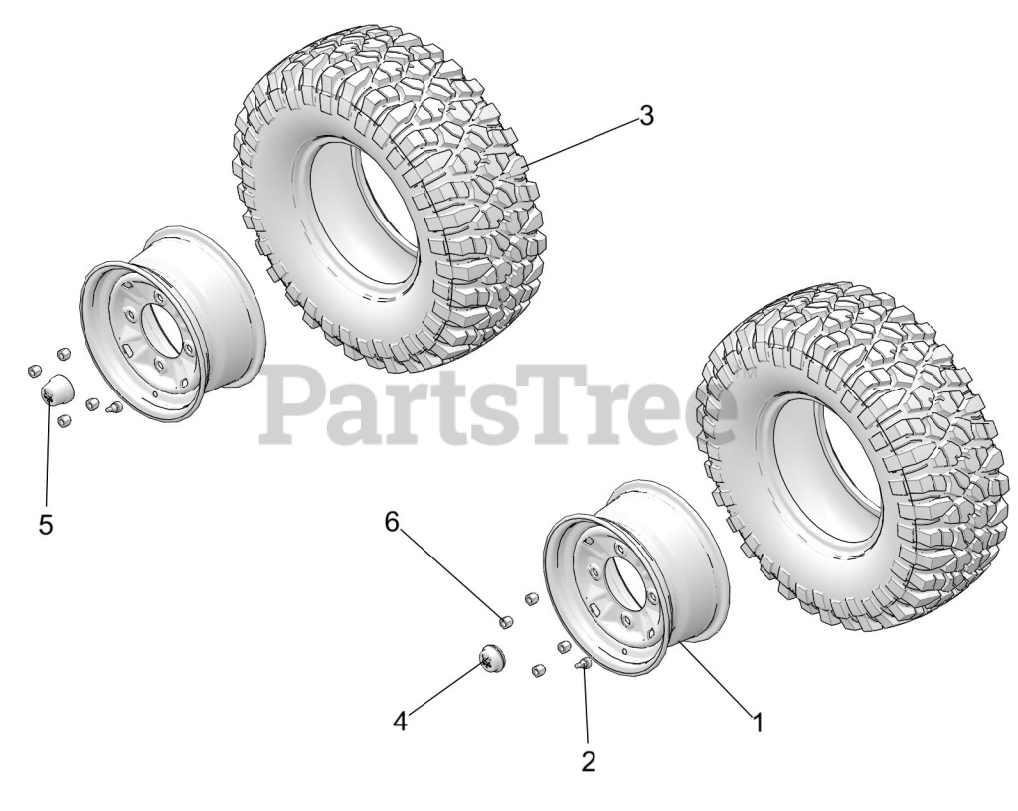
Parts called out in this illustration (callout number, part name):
1	RIM-12X6-AT-ET26.2-BLK
2	VALVE- RIM
3	TIRE-26X10-12-8PR-DI-2042
4	HUB-DUST COVER-INTRNL LIP-BLNK
5	CAP- DUST
6	NUT-LUG-M12
